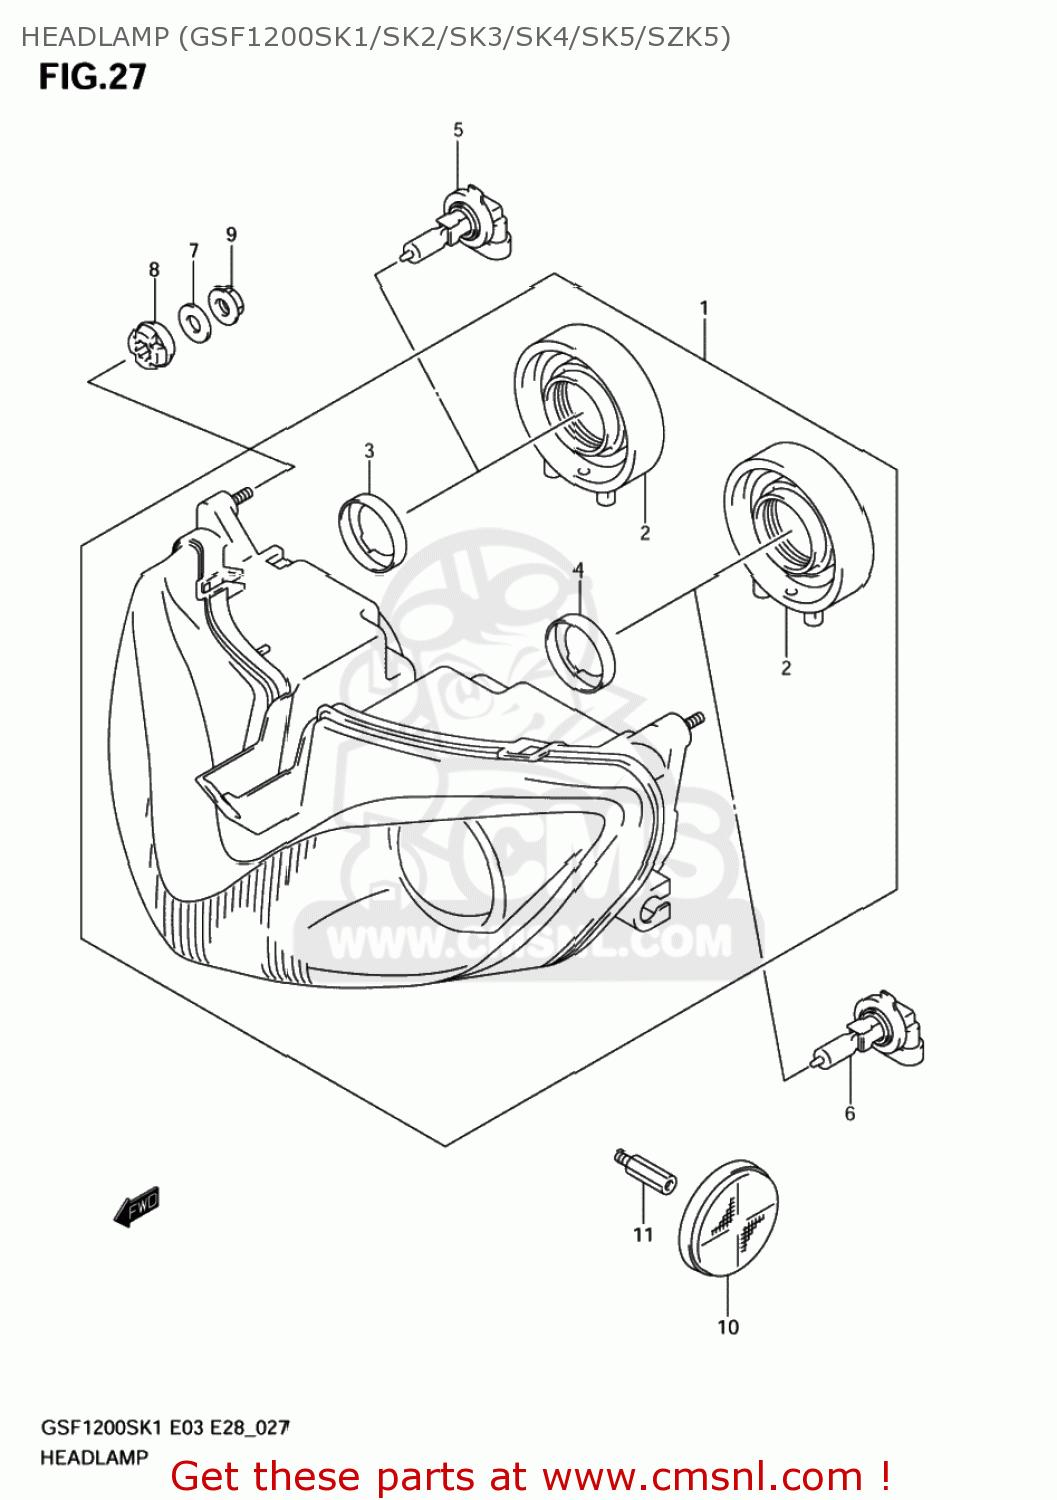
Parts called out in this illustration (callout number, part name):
1	HEADLAMP ASSY
2	SOCKET,COVER
3	RING,HEADLAMP BULB,R
4	RING,HEADLAMP BULB,L
5	BULB(12V60W,HB3,#9005)
6	BULB(12V51W,HB4,P22D)
7	WASHER(6.5X20X1.6)
8	CUSHION
9	NUT
10	REFLECTOR,REFLEX FR
11	BOLT(5X10)
